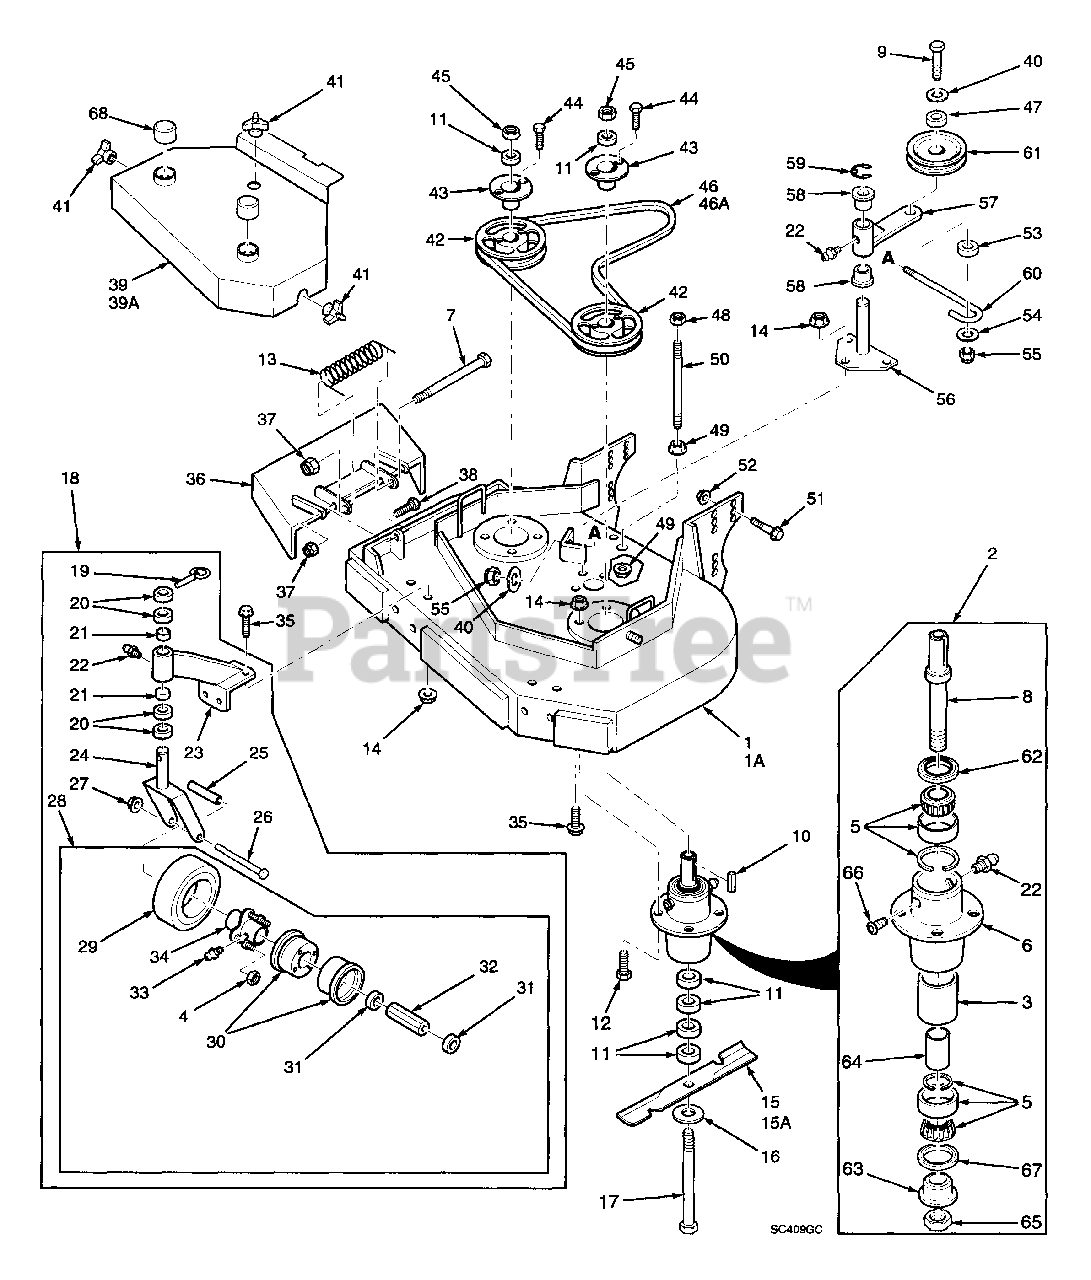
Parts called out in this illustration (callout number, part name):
1	Cutter Deck
1A	Cutter Deck
2	Cutter Spindle Assy.
3	Spacer, Outside
4	Tapered Nut, 5/16-24
5	Tapered Bearing Two
6	Spindle Housing
7	Bolt, 5/16-18 x 4-1/4" Hex Head
8	Spindle Shaft
9	Bolt, 3/8-16 x 3-1/2" Hex Head
10	Key, 1/4 x 1/4 x 2"
11	Spacer, Cutter Blade - Small
12	Bolt, 5/16-18 x 1-1/4" Hex Head
13	Spring, Chute Return
14	Nut 5/16-18 Serrated Flange
15	Cutter Blade, 16-1/2"
15A	Cutter Blade, 16-1/2" Hi Lift
16	Flatwasher, 5/8 W
17	Hex Hd Bolt, 5/8-11 x 9-1/2"
18	Caster Assembly
19	Quick Pin
20	Spacer, Caster Yoke, 1/2" long
21	Bronze Bearing
22	Grease Fitting
23	Support Assembly
24	Caster Yoke
25	Sleeve, Caster Wheel Bearing
26	Hex Hd. Bolt, 1/2-13 x 5-1/2"
27	Elastic Stop Nut, 1/2-13
28	Wheel Assy
29	Tire only, Caster Wheel
30	Rim Pair, Caster Wheel
31	Retainer, Bearing, Caster Wheel
32	Roller Bearing, Caster Wheel
33	Grease Fitting, 45 degree 1/4-28
34	Hub Assembly
35	Cpscrw, 5/16-18 x 3/4" Ser. Flg HH
36	Discharge Chute
37	Hex Nut, 5/16-18 Elastic Stop
38	Hex Hd Bolt, 5/16-18 x 1"
39	Belt Cover Assy
39A	Belt Cover Assy
40	Flat Washer, 3/8" Special
41	Wing Nut, 3/8-16
42	Pulley
43	Tapered Hub
44	Hex Hd. Bolt, 1/4-20 x 3/4"
45	Hex Nut, 5/8-11
46	Belt, Blade Drive
46A	Belt, Blade Drive
47	Spacer
48	Hex Nut, 3/8-16 Center Locknut
49	Nut, 3/8-16 Serrated Flange
50	Support, Belt Cover
51	Cpscrw, 7/16-14 x 1" Ser. Flg HH
52	Nut, 7/16-14 Serrated Flange
53	Spacer, J-Hook
54	Washer, 3/8 x 1-1/2 x 16 GA
55	Elastic Stop Nut, 3/8-16
56	Idler Pivot
57	Idler Arm Assy
58	Bronze Bearing
59	Retaining Ring, 1-1/8" Ext "E"
60	J-Hook
61	Idler Pulley, Belt Clutch
62	Seal, Cutter Spindle
63	Spindle Bushing
64	Spacer, Inside
66	Relief Fitting, Cutter Spindle
67	Seal, Cutter Spindle
68	Spindle Shield
